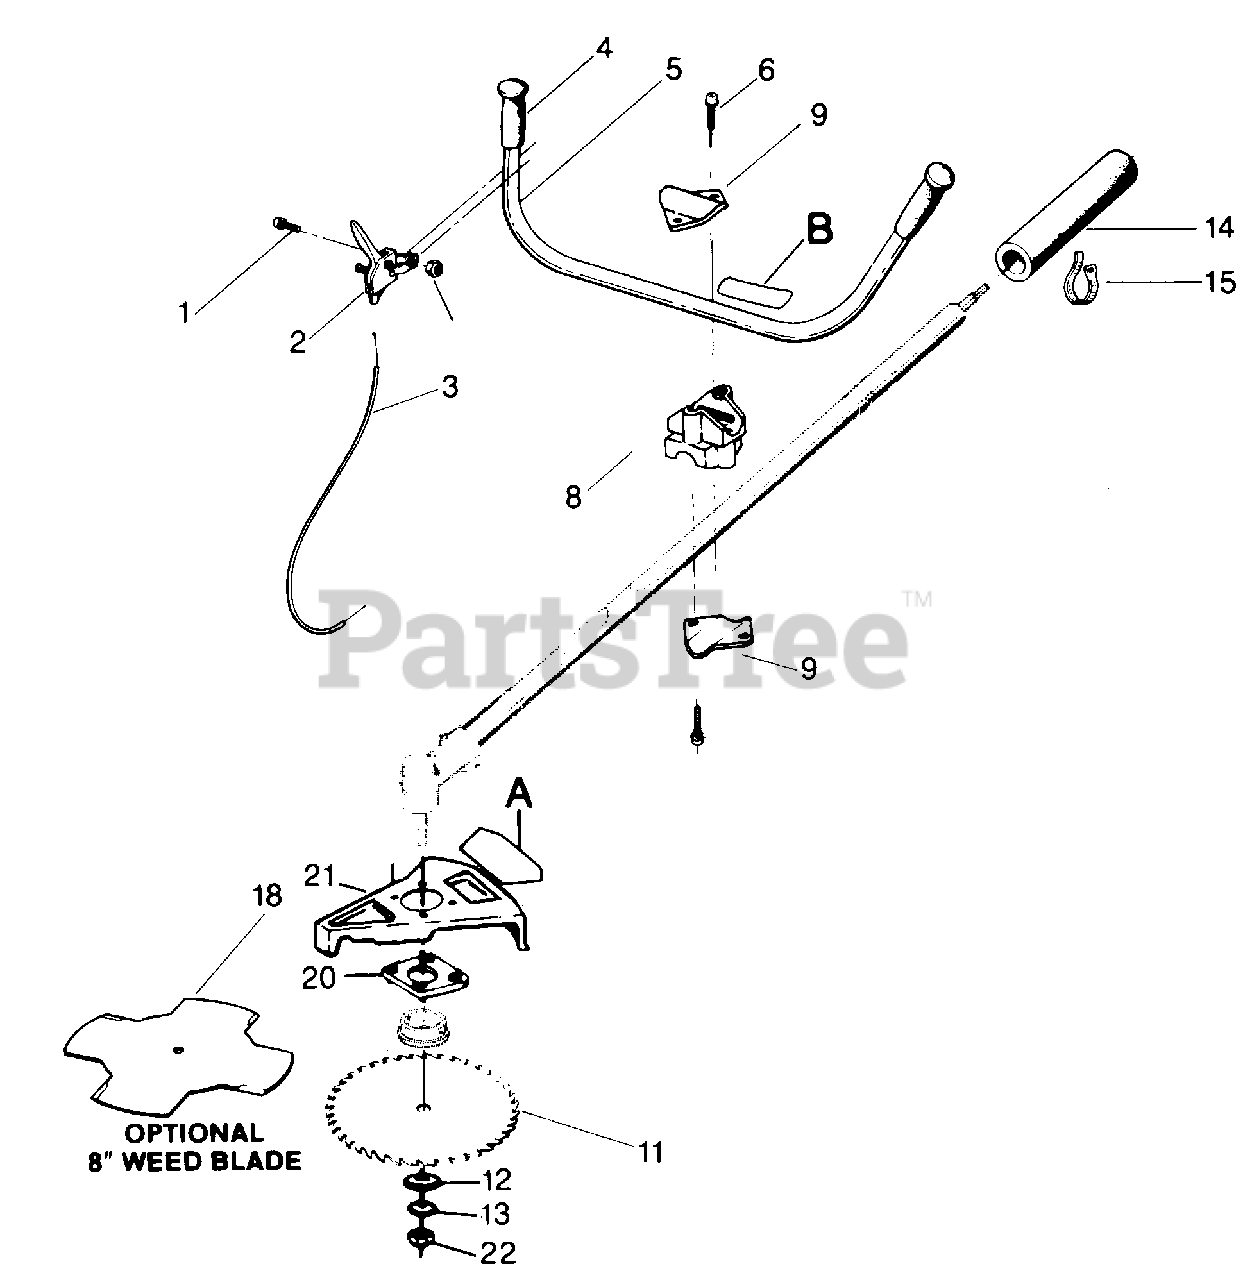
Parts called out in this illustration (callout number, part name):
1	Screw - Phil. Hd. - 5 x 25mm.- Throttle Control
2	Ass'y. - Throttle Lever
3	Cable - Throttle
4	Grip - Handlebar
5	Handlebar - "U"
6	Bolt - Clamp - Top
7	Cover - Top - Clamp
8	Clamp - Handlebar
9	Cover - Bottom - Clamp
11	Brush Blade - 10"
13	washer
14	Drive Shaft Pad
15	Tie Strap
16	Lockwasher - 10
17	Lockwasher - 10
18	Weed Blade - 8 inch - Optional
20	Shield Retention Plate
21	Shield
A	Decal - Blade Rotation (Not a serviceable part)
B	Decal - Handlebar Warning
